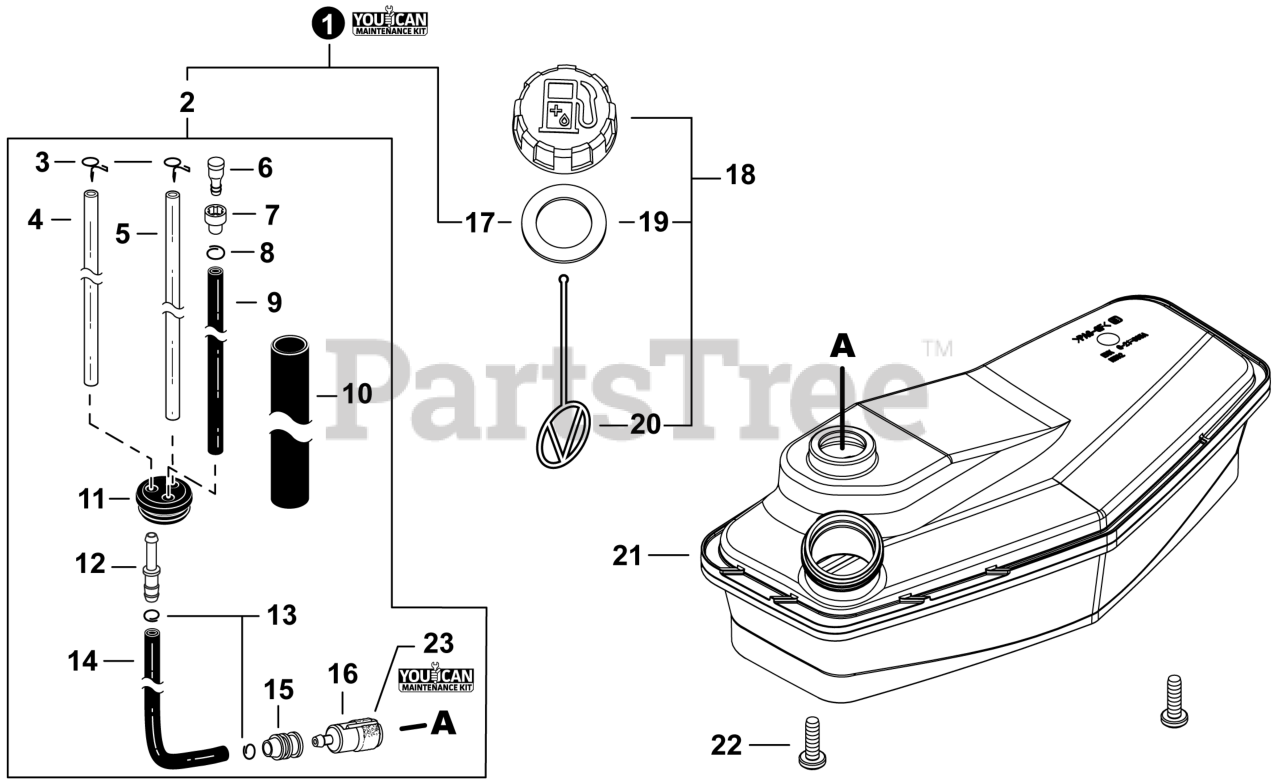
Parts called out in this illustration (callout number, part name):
1	FUEL SYSTEM KIT - YOUCANT
2	FUEL PIPE ASSY
3	CLIP, SPRING 5.2
4	PIPE, FUEL 3.5x6x225 CLEAR
5	PIPE, FUEL 3x6x250 YELLOW
6	VENT ASSY
7	HOLDER, VENT
8	CLIP 6.5 MM
9	PIPE, FUEL 3x6x40 BLACK
10	TUBE, INSULATOR 16x18x160
11	GROMMET, FUEL
12	CONNECTOR, PIPE 5x3.5
14	PIPE, FUEL 3x5x165 BLACK
16	FILTER, FUEL
17	GASKET, FUEL CAP
18	CAP ASSY, FUEL
19	GASKET, FUEL CAP
20	CONNECTOR, CAP L= 123
21	TANK ASSY, FUEL
22	BOLT, TORX 6x20
23	TUNE-UP KIT - YOUCANT
